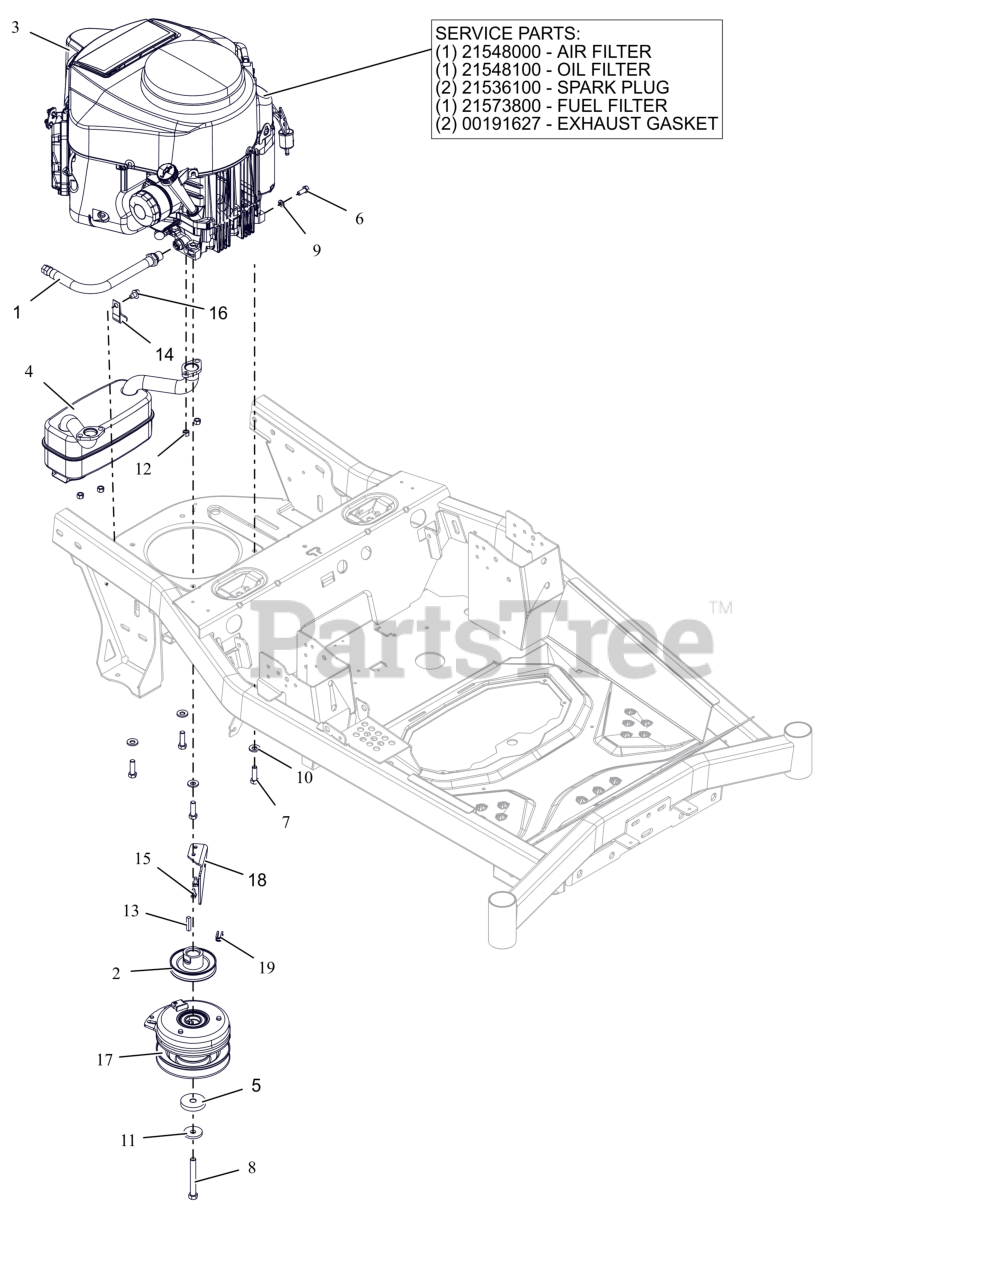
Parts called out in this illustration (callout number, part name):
1	HOSE, OIL DRAIN
2	WLDMT, PULLEY 3.75 OD X 1.003 ENGINE
3	ENGINE, KAWASAKI FR691 23HP
3	AIR FILTER, KAWASAKI FR
3	OIL FILTER, KAWASAKI FR
3	PLUG, SPARK
3	FUEL FILTER-KAWASAKI FR
3	GASKET, MUFFLER S/O
4	MUFFLER - KAWASAKI
5	SPACER, .474/.459X2.00X.350
6	BLT, HEX M8-1.25X20 G8.8 ZCC
7	BLT, HEX .38-16X1.25 G5 ZCC NT
8	BLT, HEX 0.4375-20X3.5 G8 ZCC NT
9	WSHR,LK-REG .312X.078 ZCC
10	WASHER, 3/8" SPRING DISC
11	WASHER, 7/16" SPRING DISK
12	NUT-LK-TOP-FLG M8 ZCC
13	KEY-SQ .25 X 1.25 X .25 SAE
14	J-CLAMP
15	SCR-TAP .25-20X.50 HWH ZCC
16	SCR,TAP .375-16X.50 HWH TR ZCC
17	CLUTCH- WARNER IXR-18211
18	BRKT- CLUTCH STOP
19	BSHG, CLUTCH
